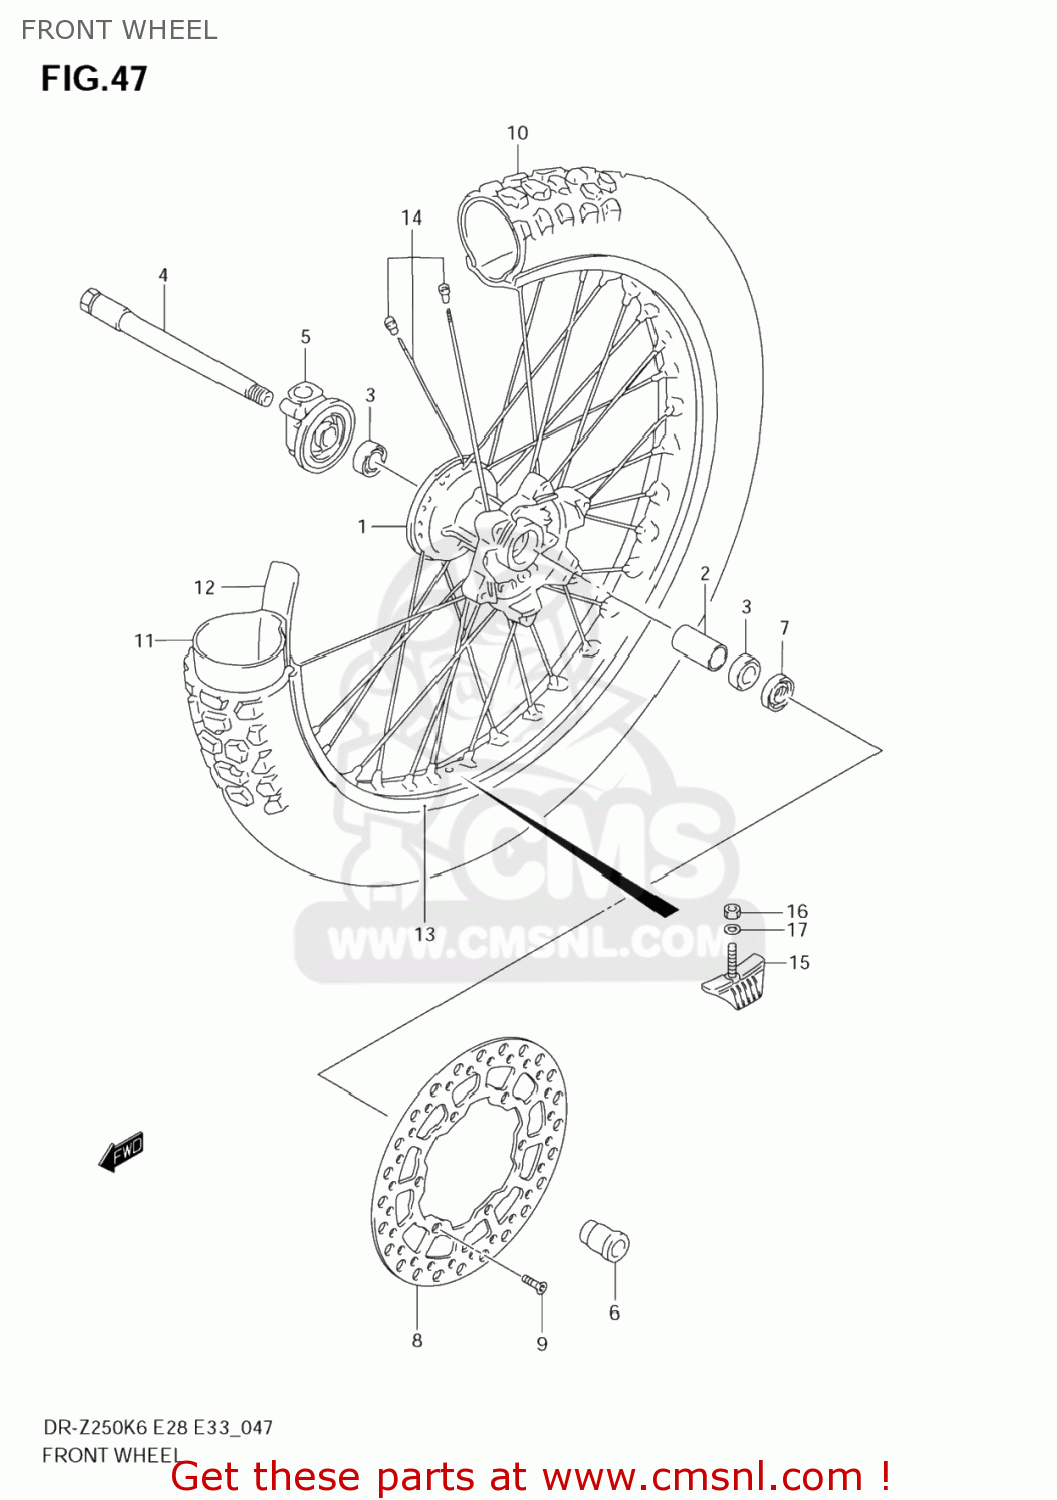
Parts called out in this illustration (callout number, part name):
1	HUB,FR WHEEL
2	SPACER,FR HUB BEARING
3	BEARING
4	AXLE,FR
5	BOX ASSY,SPEEDOMETER GEAR
6	SPACER,FR AXLE,L
7	SEAL,OIL(23X35X6)
8	DISC,FR BRAKE,L
9	SCREW(6X18)
10	TIRE,FR(80/100-21 51M D739F)
11	TUBE ASSY,WHEEL INNER
12	PROTECTOR,WHL INR TUBE
13	RIM,FR WHEEL(1.60X21)
14	SPOKE SET,FR WHEEL
15	STOPPER,BEAD
16	NUT
17	WASHER
